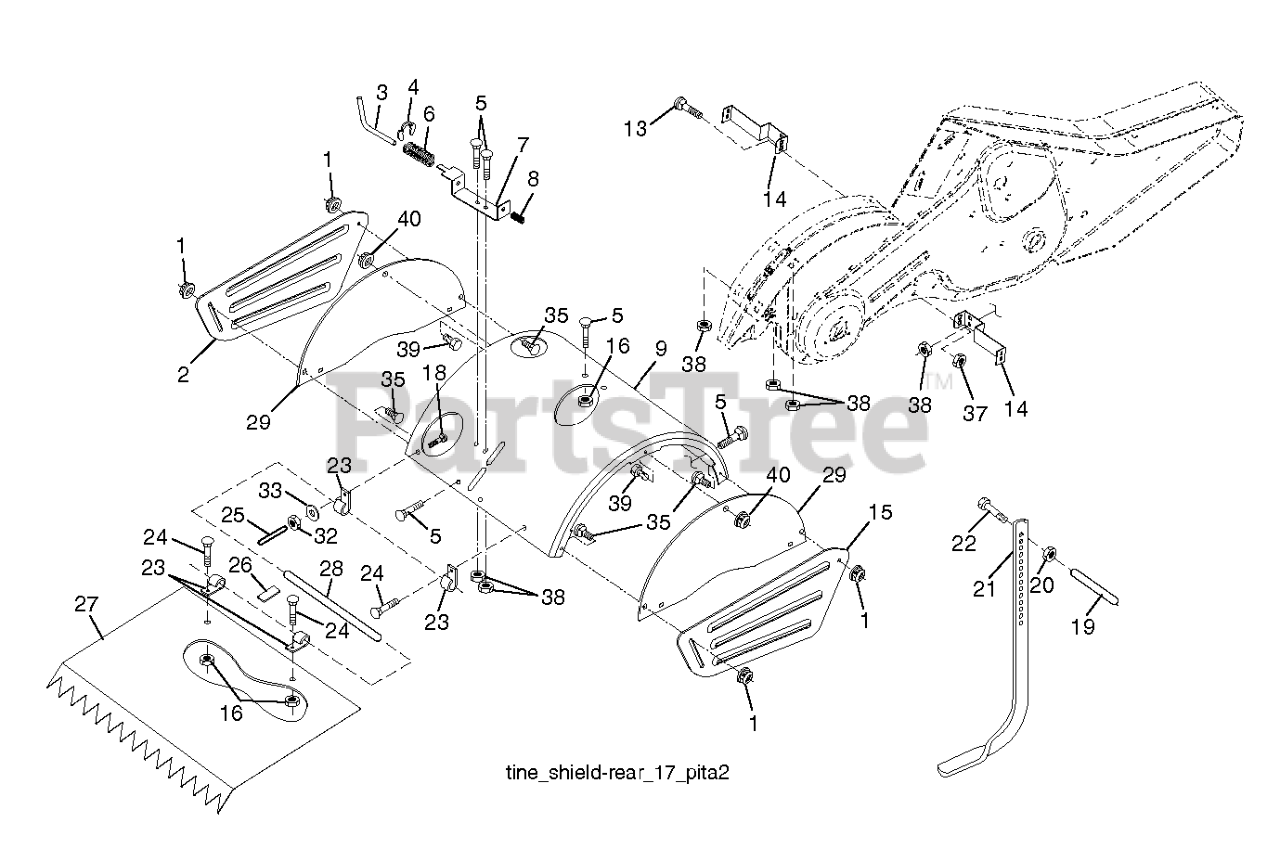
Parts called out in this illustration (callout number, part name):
1	NUT.FLANGE.5/16
2	SHIELD.PNT.SIDE.OUTER.LH.ORANG
3	STAKE PIN TI
4	RING, KLIP
5	BOLT, RDHD SQNK 5/16-18 X 3/4
7	BRACKET
8	SPRING CRT
9	SHIELD.TINE.TILLER.ORANGE
13	BOLT.CARRIAGE.5/16-18
14	BRACKET.TINE.SHIELD.TILLER.BLA
15	SHIELD.SIDE OUTER.RH.ORANGE
16	NUT T
20	NUT.HEX.3/8-16UNC
21	REPL BY 532 10 21-56
22	BOLT.375-16
24	BOLT
25	VINYL CAP TI
26	PAD IDLER TI
27	SHIELD.LEVELING.17".ORANGE
28	PIN.HINGE.TILLER
29	SHIELD.TINE.SIDE.ORANGE
32	NUT
33	LOCKWASHER
35	BOLT.CARR.5/16-18X5/8.SHORT
37	NUT.71038.31-18.HEX.NYLOCK
38	NUT
39	BOLT.HEX.HD.WASHER.5/16-18X.75
40	NUT.SPEED.5/16-18
